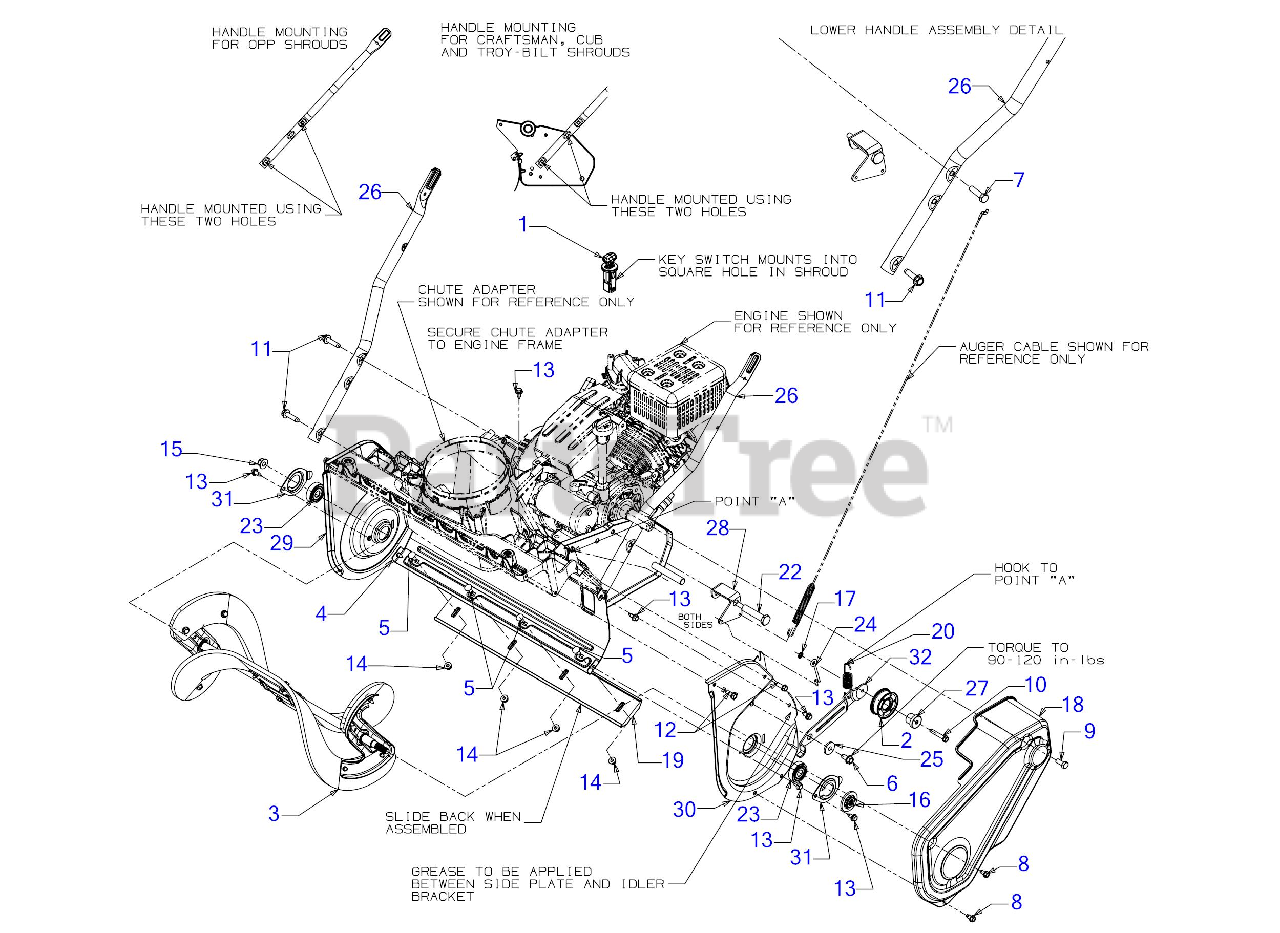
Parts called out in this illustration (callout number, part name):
1	IGNITION SWITCH
2	IDLER PULLEY ASSEMBLY
3	21" AUGER ASSEMBLY
5	CARRIAGE BOLT 1/4-20 x .62
6	SCREW 5/16-18 x .750
7	SCREW 5/16-24 x 1.25 GR5
8	SCREW 1/4-20 X.500
9	SCREW 5/16-24 x .750 GR5
10	SCREW 1/4-20 x 1.50"
11	SCREW 5/16-18 x 1.25
12	SCREW 1/4-15 x .750
13	SCREW 1/4-20X.625
14	FLANGE LOCK NUT
16	PULLEY HUB 1/2"
17	RETAINER-BOLT .25ID x .50OD
19	SHAVE PLATE
20	EXTENSION SPRING
22	SHOULDER BOLT
23	BALL BEARING
24	WIRE DRIVE CABLE SUPPORT
25	SHOULDER SPACER
27	SHOULDER SPACER
28	CLUTCH CABLE BRACKET
32	IDLER BRACKET
